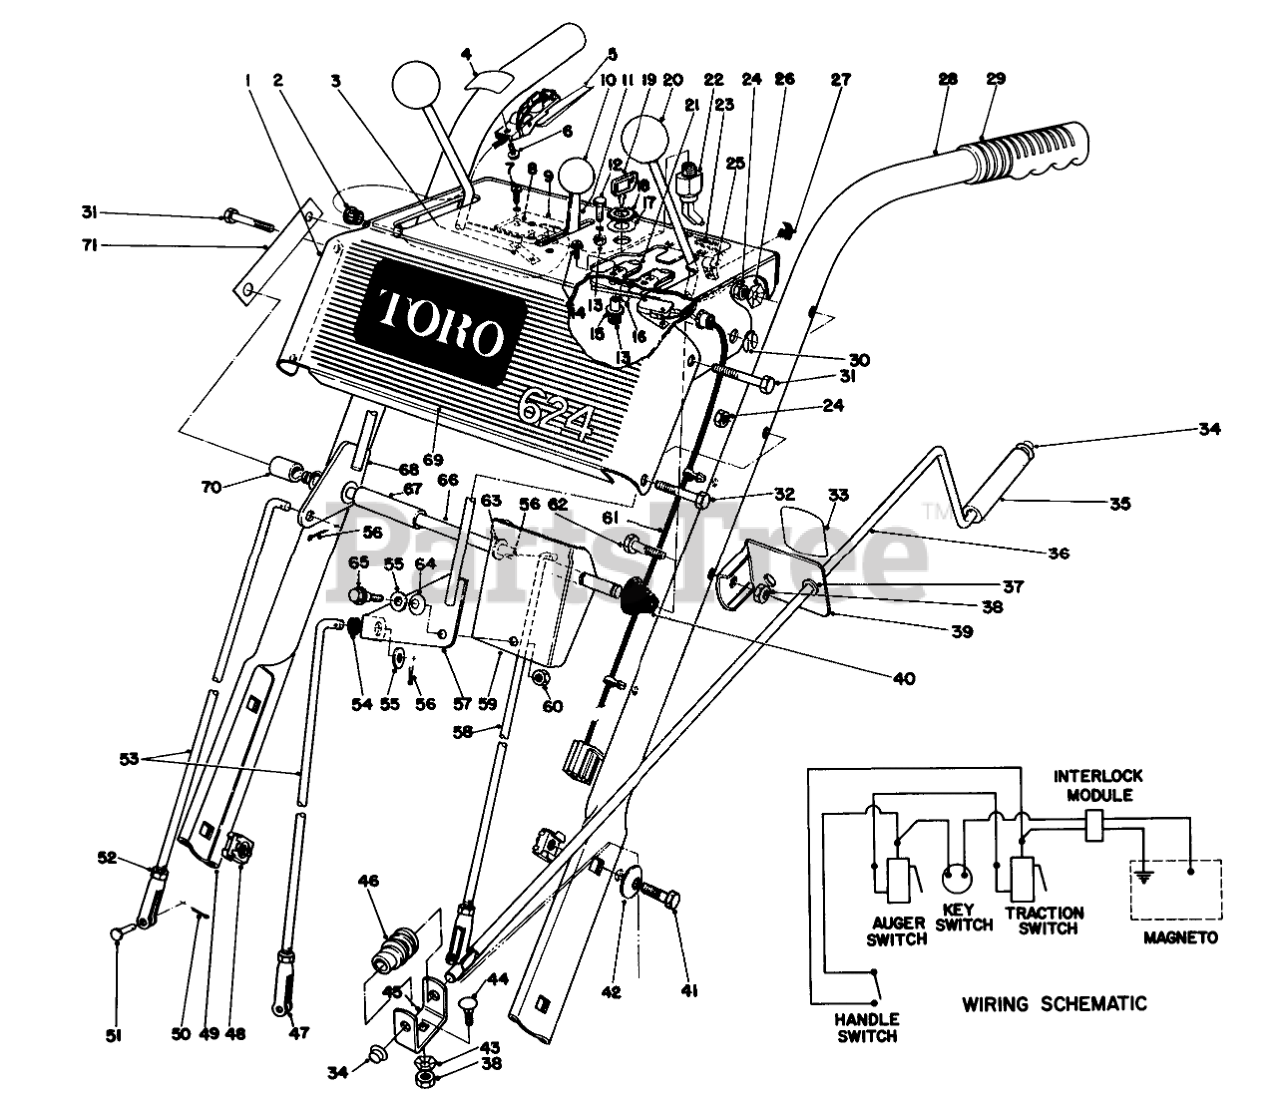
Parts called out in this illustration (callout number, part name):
1	ESCUTCHEON PLT B
2	BUSHING NYLON
3	NUT-SPEED
4	INTERLOCK DECAL
5	INTERLOCK HDLE SWITCH
6	SCREW
7	SCREW-SPH
8	SWITCH-MICRO
9	SWITCH MTG PAD
10	CONTROL KNOB
11	THROTTLE CONTROL
12	HEX HEAD SEMS 10-24X1/2
13	NUT-LOCK, NI
14	10-24 X 7/8 RND HD MS
15	INTERLOCK SPACER
16	INTERLOCK SPRING
17	WASHER-TOOTH, INTERNAL
18	NUT-HH
19	KEY-IGNITION
21	INTERLOCK SLIDE
22	On-Off Switch (Incl. Ref. #17 & 18)
23	INSTR DECAL
24	NUT-LOCK, CONE
25	WIRE CLAMP
26	Washer
27	Mounting Stud
28	LEFT HANDLE
29	Grip Handle
30	RING-CLIP
31	SCREW-HH
32	SCREW-HH
33	DECAL-CHUTE DIRECTION
34	RETAINER-PUSH ON
35	Grip-Rod
36	CHUTE CONTROL ROD
37	Bushing
38	NUT-LOCK, NI
39	Chute Control Rod Mounting (Incl. Ref. #33 & 37)
40	CONICAL SPRING
41	SCREW-HH
42	WASHER-SPRING
43	WASHER-LOCK
44	BOLT-CARR
45	BRACKET-WORM
46	GEAR-WORM, CHUTE
47	CLEVIS
48	Retained Nut
49	HANDLE RIGHT
50	PIN-COTTER
51	PIN-CLEVIS
52	NUT-HJ
53	SPEED SELECTOR ROD
54	GROMMET-RUBBER
55	WASHER-FLAT
56	PIN-COTTER
57	SHIFT LEVER WA
58	TRACTION CONTROL ROD
59	SHIFT BRACKET
60	NUT-LOCK, CONE
61	WIRE HARNESS INTERLOC
62	SCREW-HH
63	WASHER-FLAT
64	7/16 SPRING WASHER
65	SHOULDER SCREW
66	PIVOT ROD
67	SHIFT LEVER SPACER
68	LEVER WA
69	DECAL - ESCUTCHEON 624
70	AUGER LEVER SPACER
71	ESCUTCHEON SUPT STRAP
